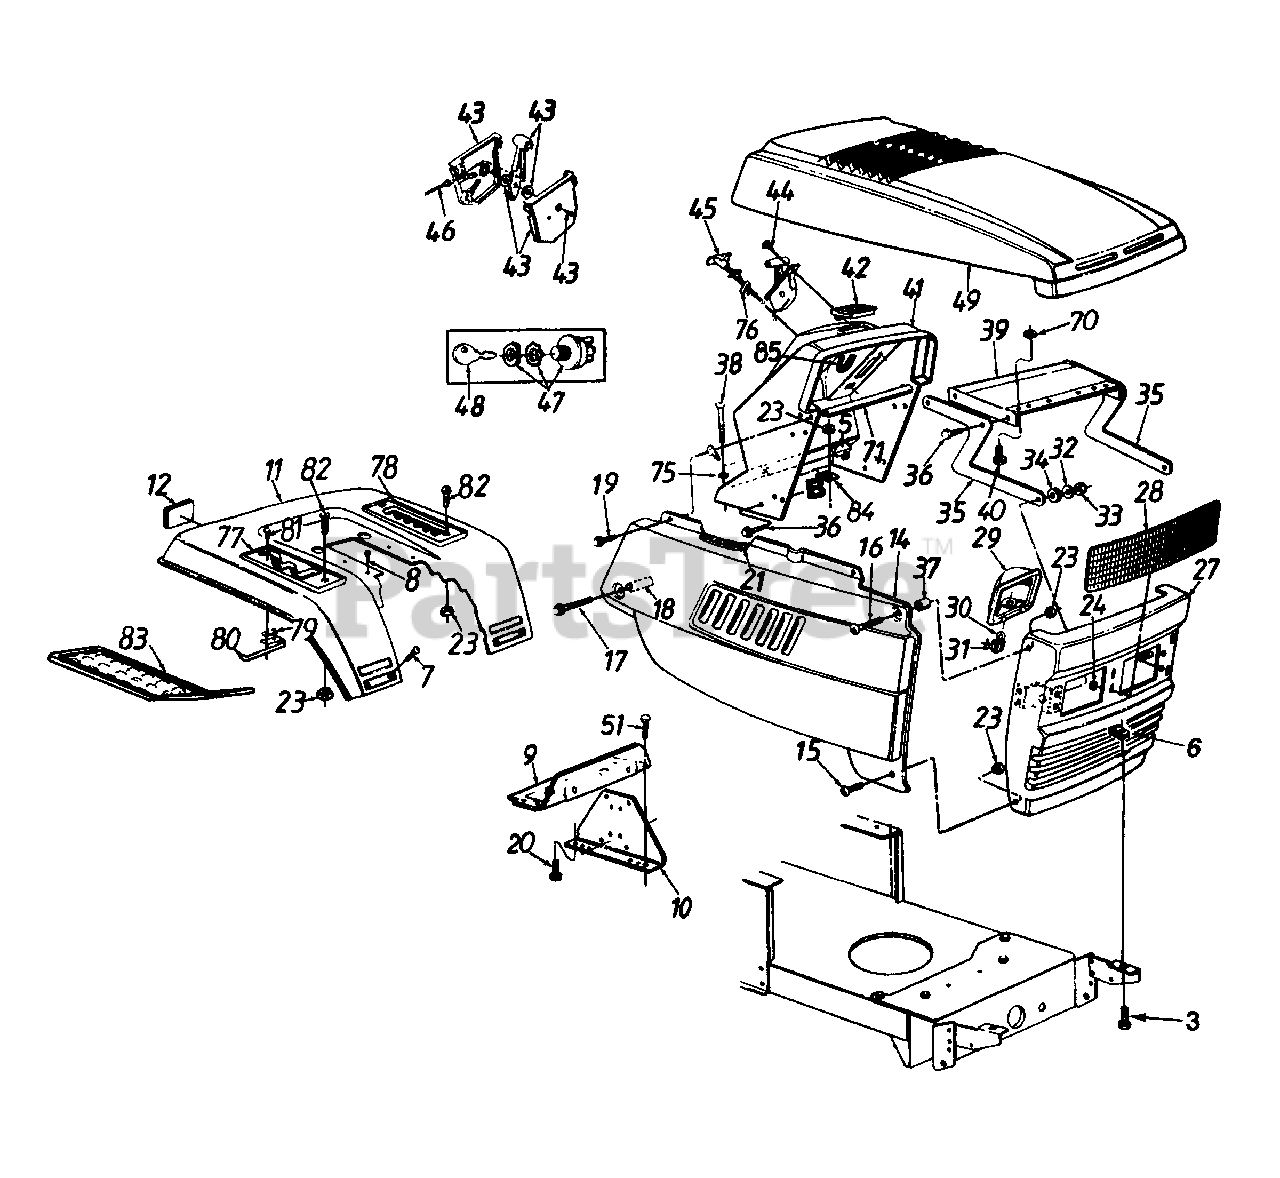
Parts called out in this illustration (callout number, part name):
3	Hex Bolt 5/16-18 x .75" Lg.
5	Light Switch
6	U-Nut 5/16-18 Thd.
7	Carriage Bolt 1/4-20 x .5" Lg.
8	Hex Wash. Hd. Tap Scr. 5/16 x .75" Lg.
12	Reflector
16	Truss Mach. Scr. 1/4-20 x 1.0" Lg.
17	Hex Wash. TT-Tap Scr. 1/4-20 x 1.75" Lg.
18	Spacer .26" I.D. x 1.32"
19	Hex Rolling Tap Scr. 1/4-20 x .75" Lg.
20	Hex Bolt 1/4-20 x .62" Lg.
21	Trim Strip - 18" Lg.
23	Hex Sems Nut 1/4-20 Thd.
24	Speed Nut 5/16" Thd.
29	Headlamp Housing
30	Headlamp
31	Twist Lock Lamp Socket
32	Bell-Wash. .345" I.D. x .88"
33	Hex L-Nut 5/16-18 Thd.
34	Rubber Washer
37	Spacer .262" I.D. x .31"
38	Carriage Bolt 1/4-20 x 1.25" Lg.
41	Dash
42	Ammeter
43	Throttle Control Box Ass'y.
44	Mach. Scr. #10 x .44" Lg.
45	Choke Control
46	Throttle Control Wire
47	Ignition Switch
48	Ignition Key
51	Hex Wash. Hd. B-Tap Scr. 5/16-18 x .5" Lg.
70	Fl-Wash. .406" I.D. x .812" O.D.
71	Grille Support Tube
75	Retaining Nut
76	Choke Retainer
77	Forward/Reverse Index Brkt.
78	7-Speed Index Brkt.
79	Insulator Nut Plate
80	Reverse Safety Switch
81	Hex Wash. Hd. AB-Tap Scr. #8 x .5" Lg.
82	Truss Mach. Scr. 1/4-20 x .75" Lg.
83	Rubber Foot Pad - L.H.
84	Dash Fastening Tab
85	Cable Tie
